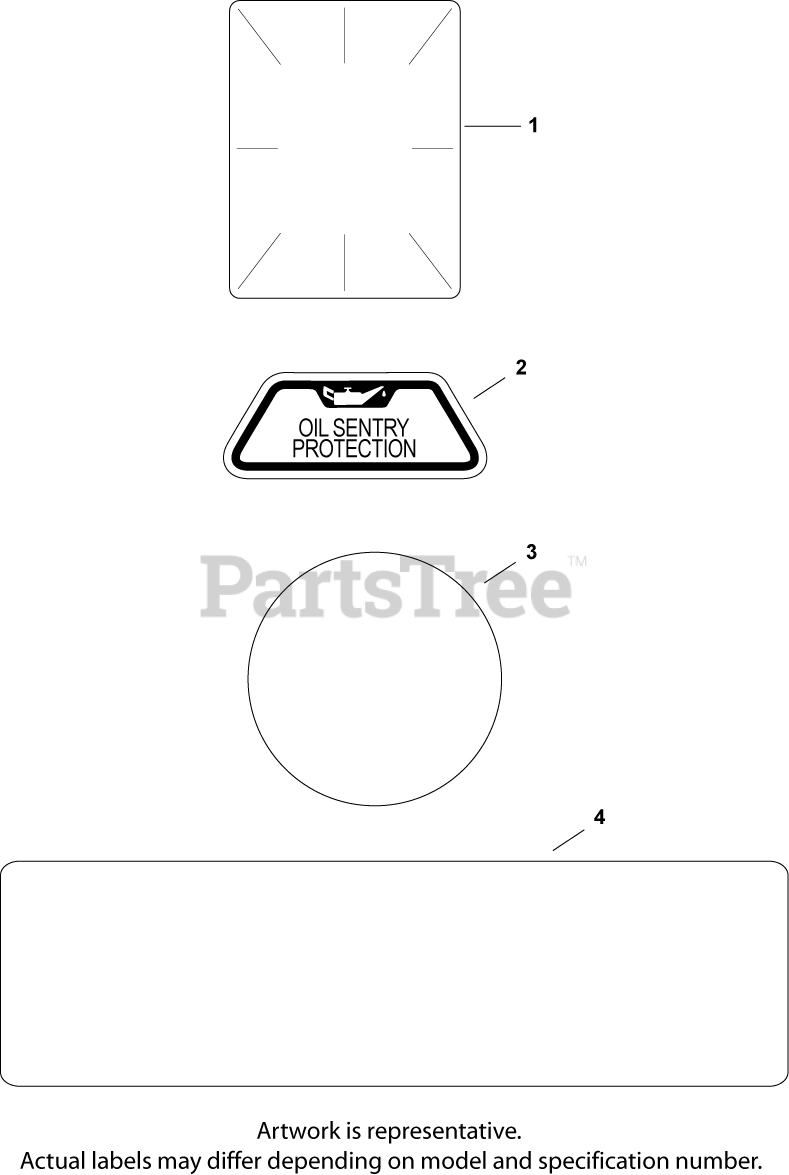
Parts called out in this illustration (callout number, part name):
1	DECAL, CLEAR LAMINATE USE 25 113 70-S
2	DECAL, OIL SENTRY - (#DSC)
3	LABEL, (ROUND KOHLER GOLD)-USE 24 113 18
4	DECAL, 20 HP
